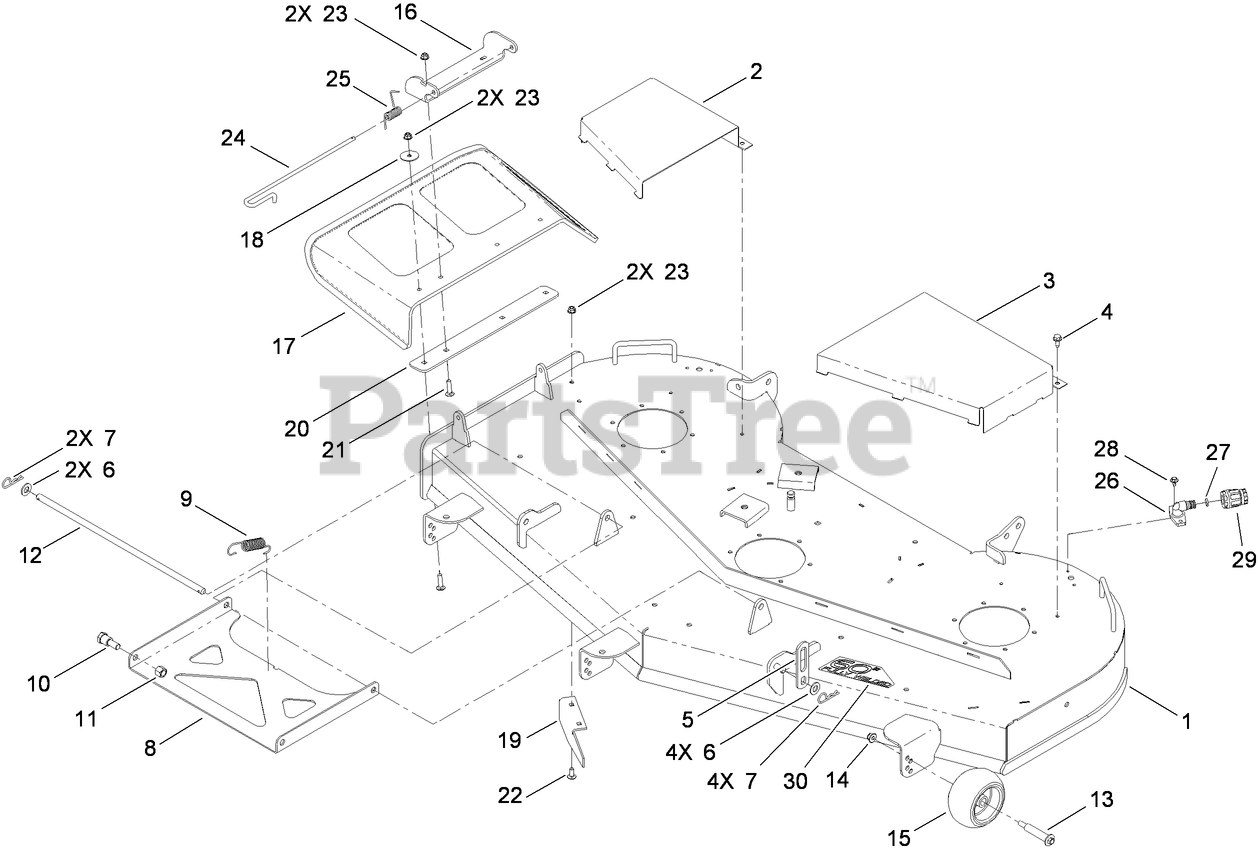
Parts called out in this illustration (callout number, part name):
4	SCREW-HWHTF
5	LINK-LIFT
6	WASHER-FLAT
7	PIN-COTTER
8	PAN-PIVOT, DECK
9	SPRING-EXTENSION
11	NUT-LOCK, NI
12	ROD-DECK, PIVOT
13	BOLT-SHOULDER
14	NUT-HF, NI
15	ROLLER-SCALP, ANTI
16	BRACKET-DEFLECTOR, UPPER
17	DEFLECTOR
18	WASHER-FLAT
19	BAFFLE-CUTOFF
20	PLATE-DEFLECTOR
21	SCREW-CARR
22	SCREW-CARR
23	NUT-HF, NI
24	PIN-CHUTE
25	SPRING-TORSION
27	O-RING
28	SCREW-HHFTF
29	CONNECTOR-HOSE
